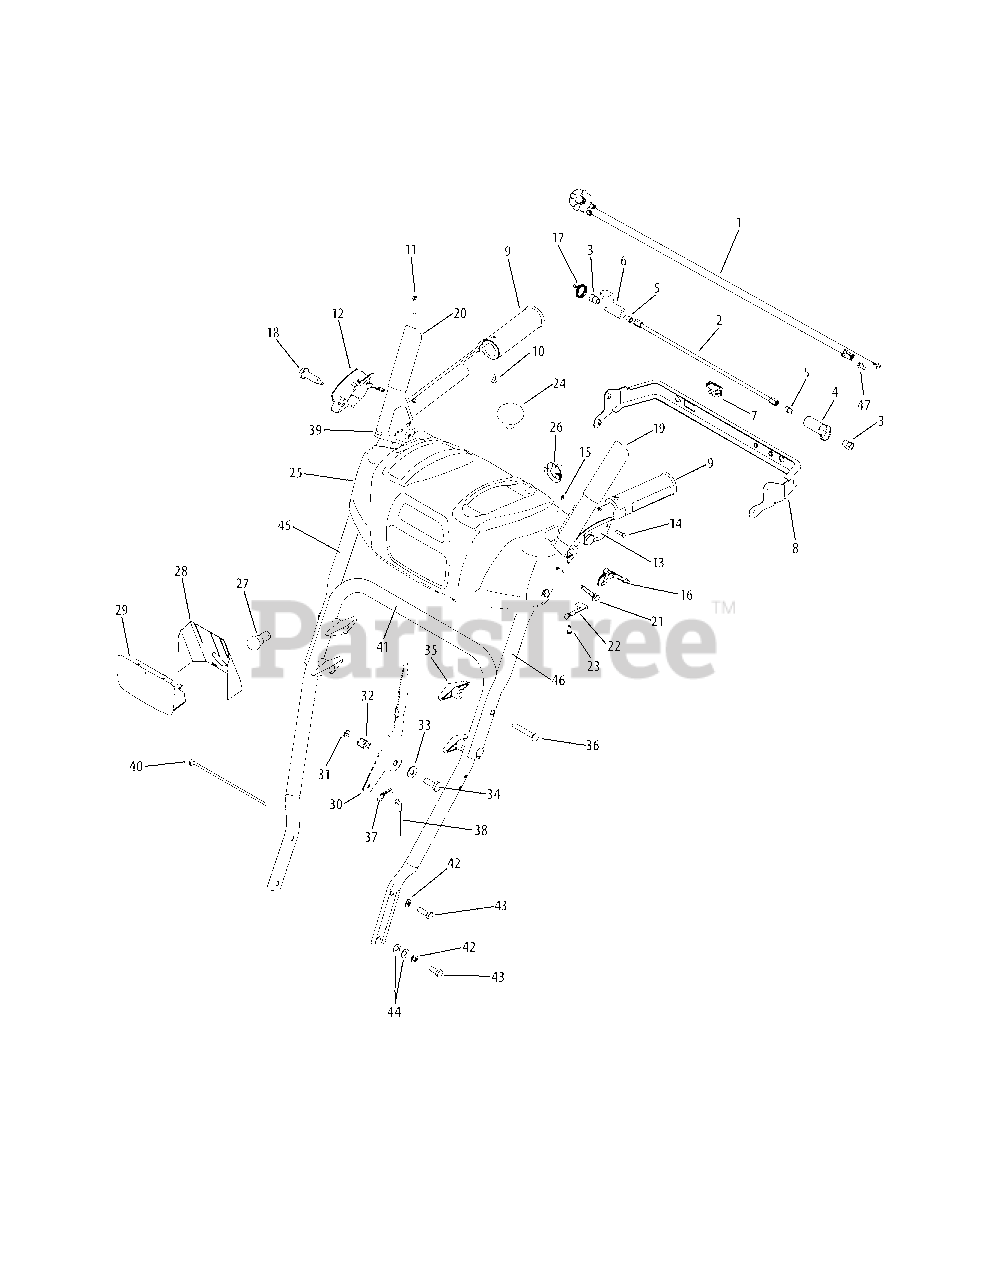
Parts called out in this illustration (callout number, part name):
1	Wire Harness
2	Clutch Lock Rod Assembly
3	Hex Shoulder Nut, 1/4-20
4	Clutch Lock Cam
5	Socket Cap Screw 1/4-20 x .50
7	Heated Grip Switch
8	Panel Bracket
9	Heated Grip
10	AB Screw, #10-16 x .625
11	Machine Screw, #10-24 x 1.375
12	Clutch Lock Handle Assembly, RH
13	Clutch Lock Handle Assembly, LH
15	E-Type Ring, .375
16	Clutch Trigger Lock
17	Torsion Spring, .8156 ID x .3038
18	Shoulder Screw, .437 x 1.345 x 1/4-20
19	Engagement Handle Assembly, LH
20	Engagement Handle Assembly, RH
21	Hex Washer Screw, 1/4-20 x 1.625
22	Clutch Lock Spring
23	Hex Washer Screw, #8-16 x .50
24	Shift Knob
25	Handle Panel
26	Light Socket
27	Lamp
28	Lens Label
31	Flange Lock Nut, 1/4-20
32	Compression Spring, .39 x .60 x .88
33	Flat Washer, .385 x .87 x .06
34	Shoulder Screw, .374 x 1.05
35	Knob Assembly, 5/16-18
36	Carriage Screw, 5/16-18 x 2.25
37	Click Pin, .092 x 1.64
38	Speed Selector Cable
39	Rubber Bumper, .62 x .22
40	Cable Tie, 3/16 x .05 x 7.43
41	Lower Handle
42	Lock Washer, 5/16
43	Hex Bolt, 5/16-18 x .75
44	Flat Washer, .344 x .688 x .065
45	Upper Handle, RH
46	Upper Handle, LH
47	Screw, 1/4-20 x .500
